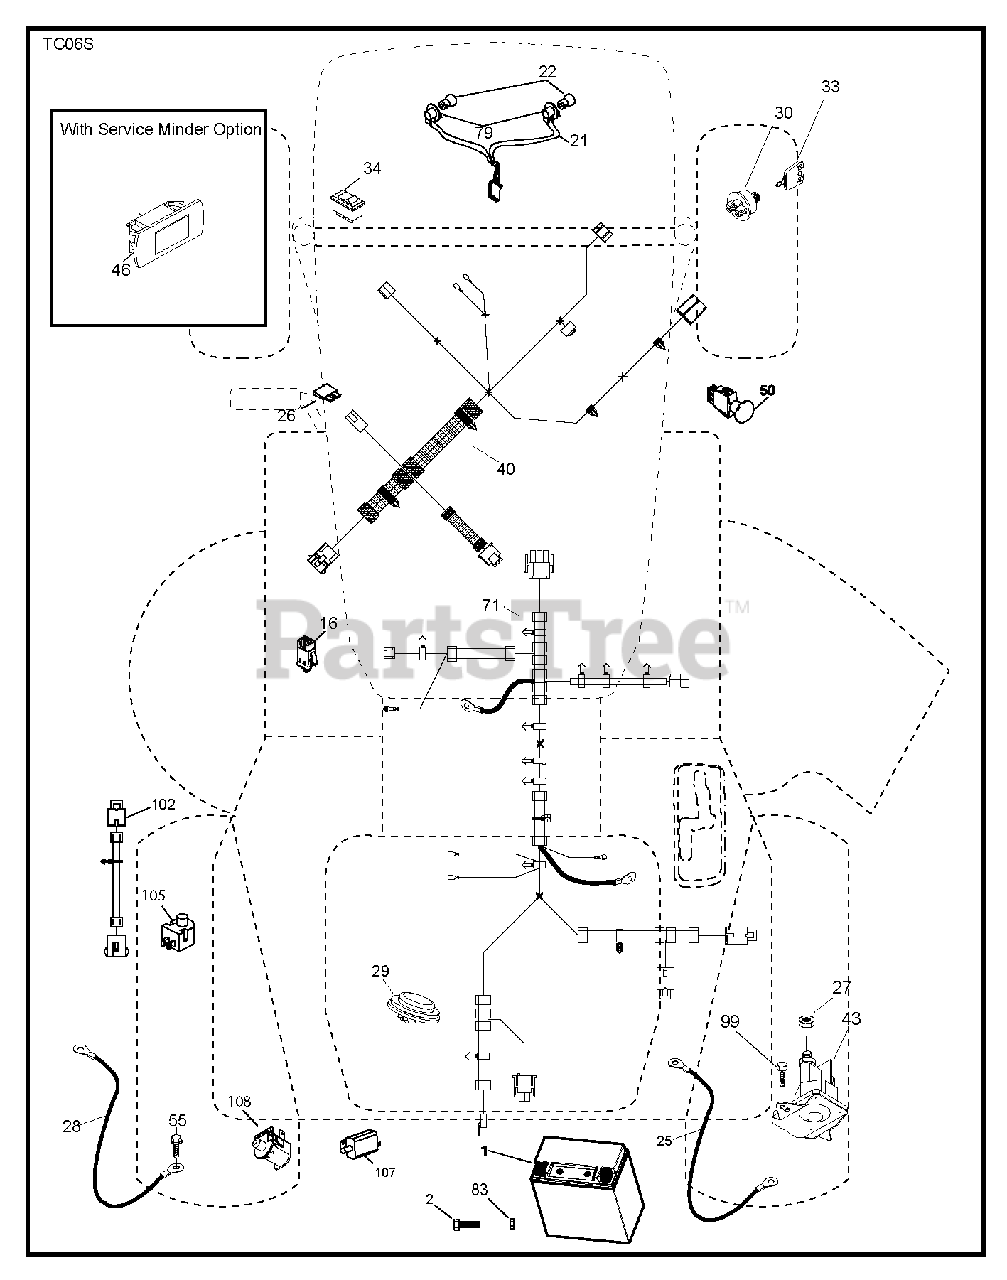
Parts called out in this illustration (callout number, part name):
1	BATTERY BATTERY 14AH 12V LEOC
2	SCREW.HEX.HEAD.CAP.M6 X1.12W
16	SWITCH INTERLOOK PUSH-IN
21	HARNESS.LIGHT W/4152J BULBS
25	CABLE BATTERY CABLE
26	FUSE 20AMP
27	NUT
29	SWITCH.SEAT.DELTA.OPC.
30	SWITCH.IGN.DELTA.W.LGH.ROS
33	KEY.CHAIN.BLISTER.PACK.GEN.INT
40	WIRING HARNESS
43	SOLENOID.W/BRASS.PLUNGER
50	RB PTO.SWITCH.8 TERMINAL.BLACK
55	SCREW 5/16"
79	BULB HOLDER ASM.
83	NUT NUT SQUARE
99	SCREW
102	HARNESS ASSY
105	REVERSE SWITCH
107	.WITCH.FULL BAGGER.INDICATOR
108	SWITCH.SNAPMOUNT.NC
